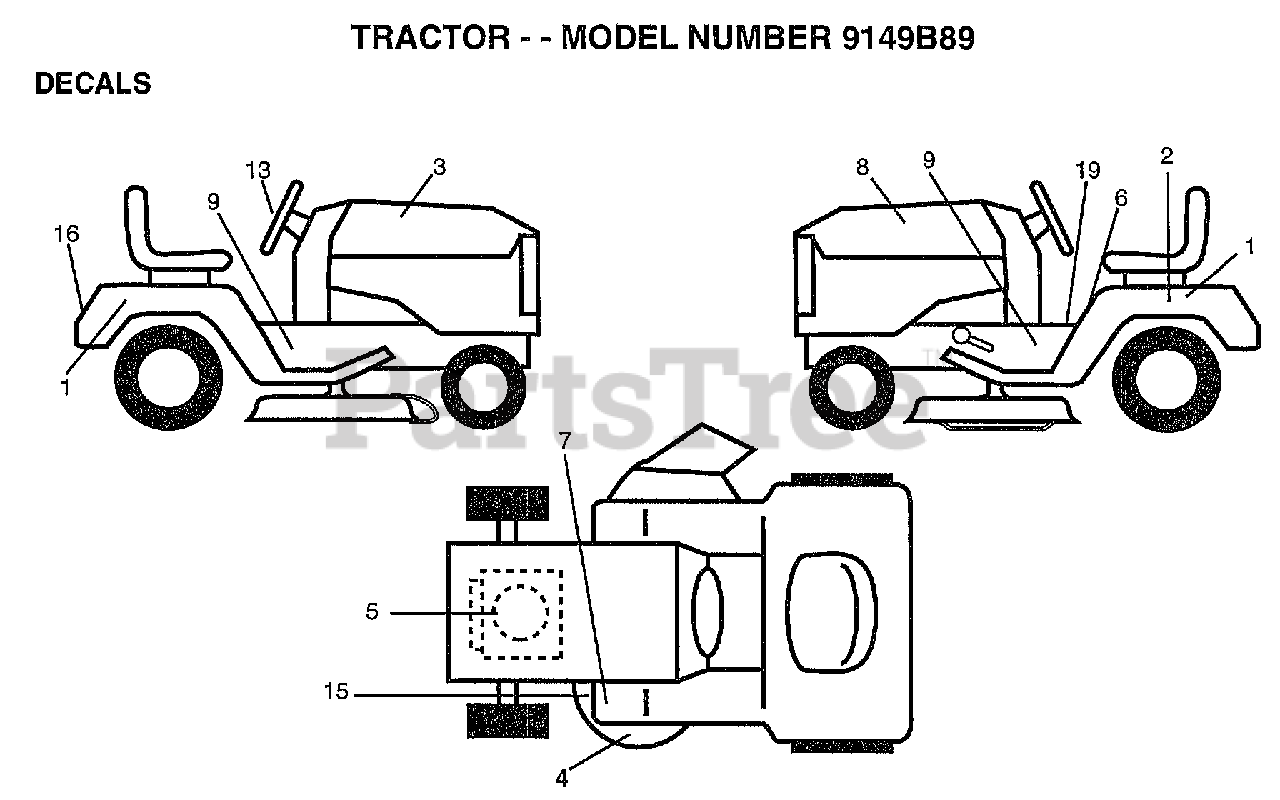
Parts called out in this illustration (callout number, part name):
1	DECAL.FENDER.WIZ
2	DECAL.BATRY.3-3908
3	DECAL.HOOD.RH
4	DECAL DECK WIZ +
5	DECAL.ENGINE
6	"DECAL DANGER,FEND"
8	DECAL.HOOD.LH
9	"DECAL.CHASSIS.42"""
13	DECAL.INS.STRG.WL
15	"DECAL-SCHEM,BELT"
19	"DECAL INST,SADDLE"
